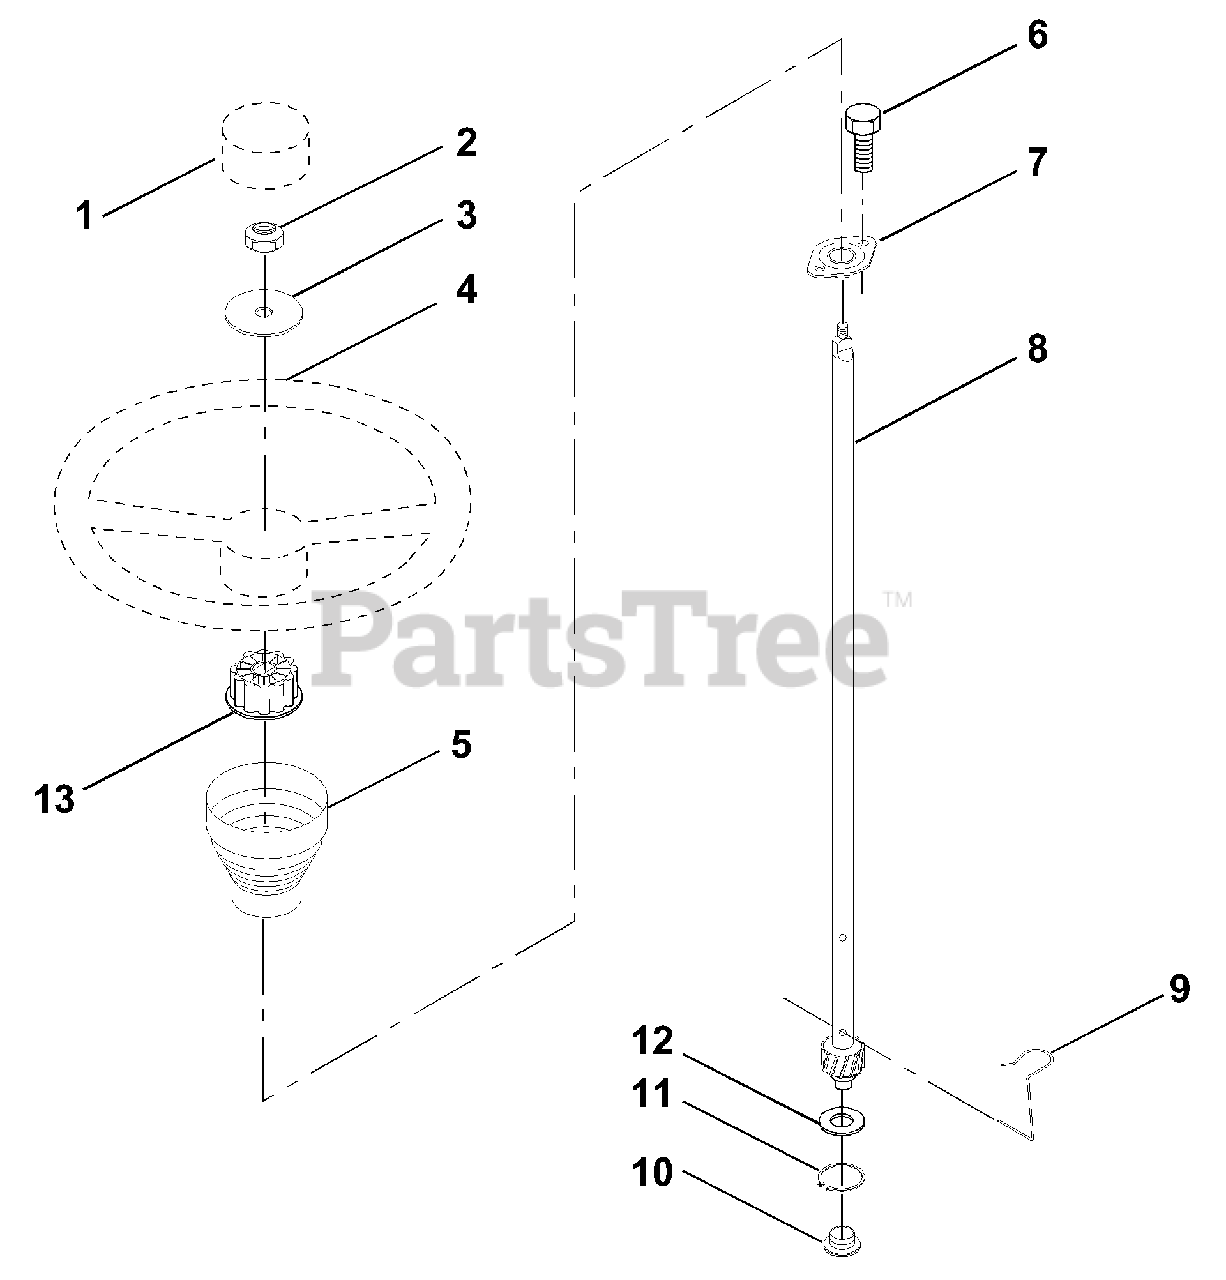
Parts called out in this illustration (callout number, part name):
1	Insert, Steering Wheel
2	Locknut 3/8-24 UNF
3	Washer 12/32 x 2-3/8 x 8 Gauge
4	Steering Wheel
5	Sleeve, Steering
6	Screw, Hex Head #10-16 x 1/2
7	Bushing, Steering
8	Shaft, Steering
9	Clip, Steering
10	Bushing, Lower, Steering
11	Ring, Retaining
12	Washer 21/32 x 1 x 16 Gauge
13	Adaptor, Steering Wheel
